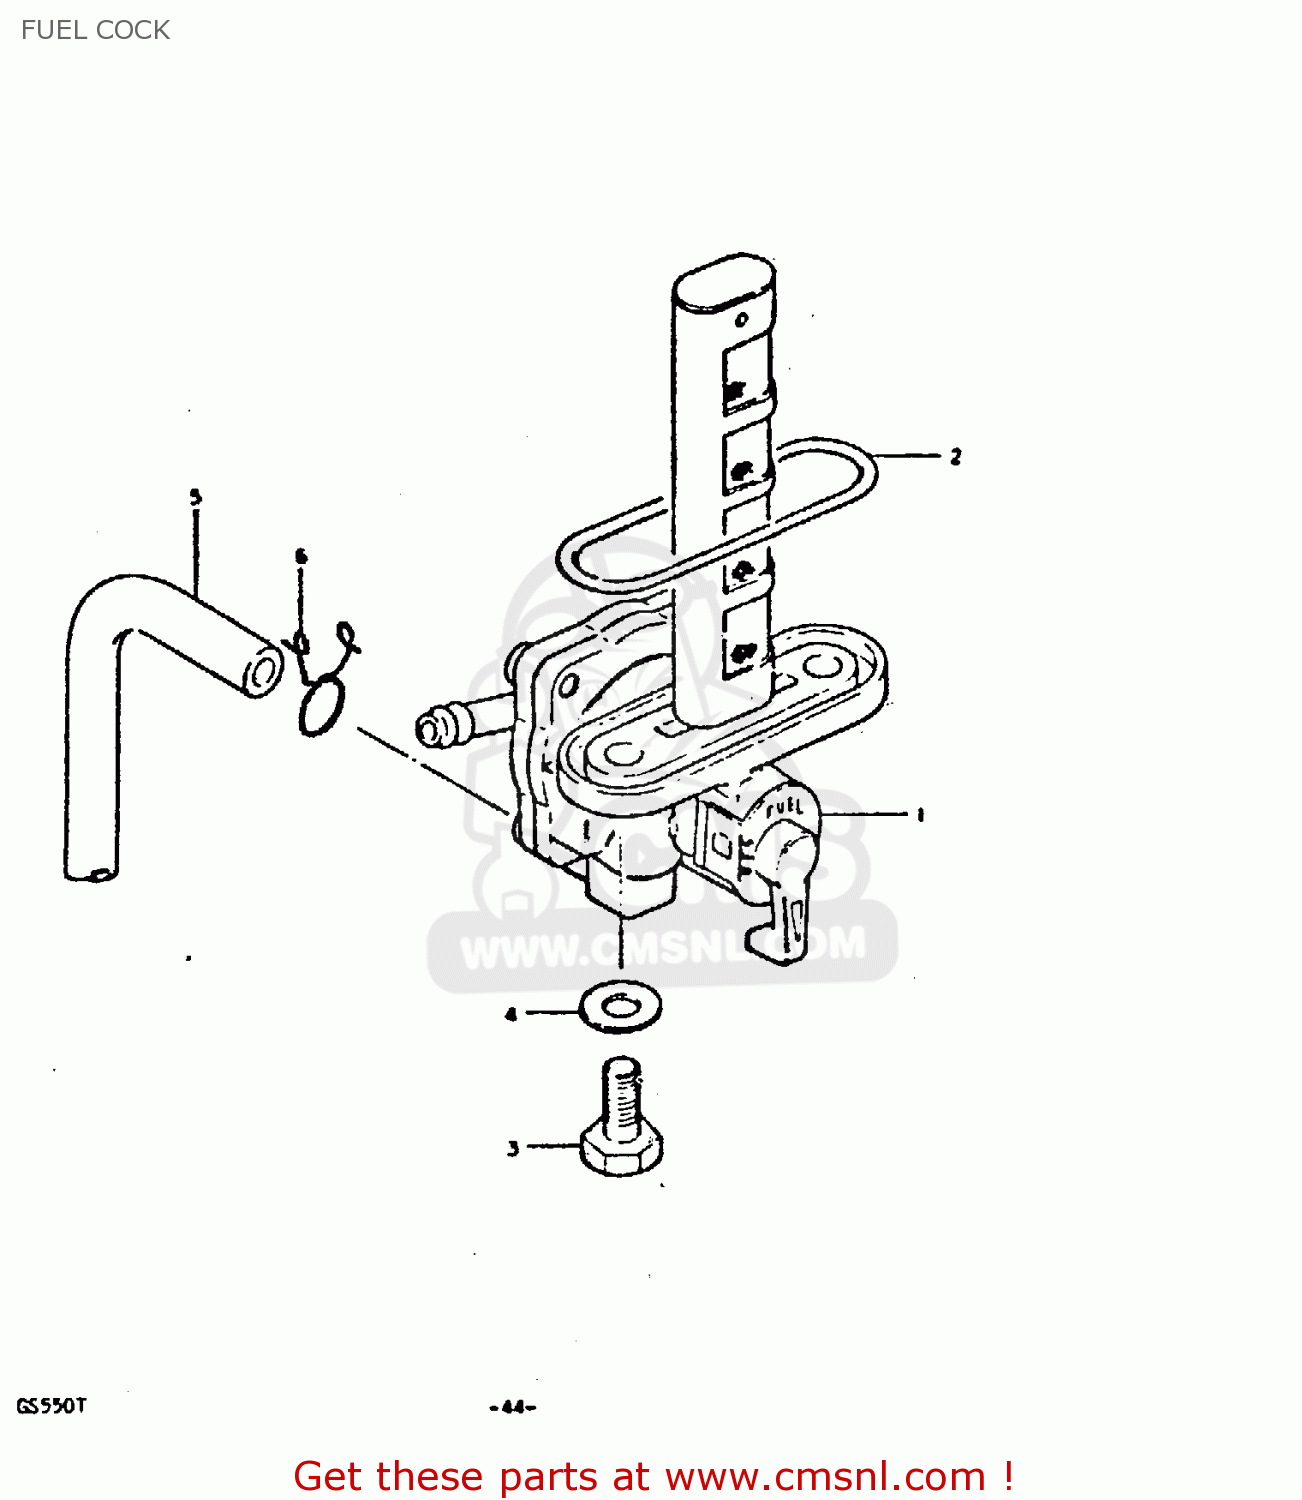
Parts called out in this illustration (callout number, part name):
1	COCK ASSEMBLY,FUEL
2	O RING
3	BOLT(6X20)
4	GASKET
5	HOSE
6	CLIP
